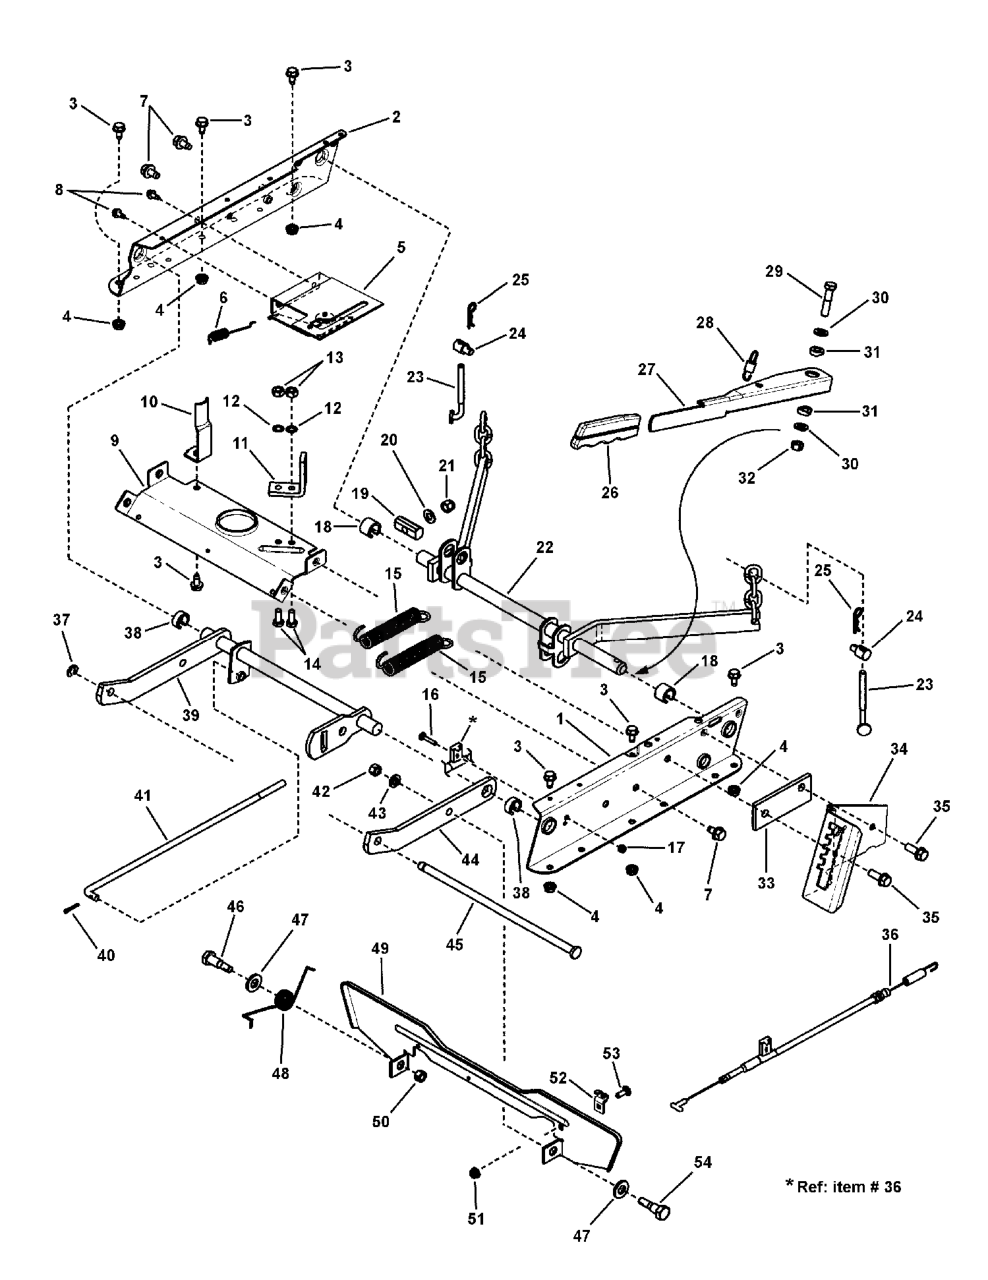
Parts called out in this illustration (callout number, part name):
1	RAIL, Deck Lift, Left Hand
2	RAIL, Deck Lift, Right Hand
3	SCREW, 5/16-18 x 5/8" Hex Washer Self-Tap
4	NUT, 5/16-18 Hex Flange Lock, GR 5
5	KIT, Clutch Plate Assembly
6	SPRING, Latching
7	SCREW, 3/8-16 x 5/8" Hex Washer Self-Tap
8	SCREW, 5/16-18 x 1/2" Hex Washer Self-Tap
9	BRACE, Top
10	GUIDE, Belt
12	WASHER, 5/16" Internal Tooth Lock
13	NUT, 5/16-24 Hex
14	SCREW, 5/16-24 x 3/4" Hex Head Cap, GR 5
15	SPRING, Assist
16	BOLT, #10-24 x 1" Flat Head Square Neck
17	NUT, #10-24 Hex Nyloc
18	RING, Rear Lift Arm (Blue)
19	PIVOT, Leveling
20	WASHER, 3/8" Flat SAE
21	NUT, 3/8-24 Hex Nyloc
22	WELDMENT, Rear Lift Arm
23	ADJUSTER, Chain (5/16-18 thread)
24	SWIVEL, Adjustable
25	HAIR PIN, 3/32 x 1-1/2"
26	GRIP, Height Adjustment Lever
27	LEVER, Height of Cut
28	SPRING, Lever
29	SCREW, 3/8-24 x 1-3/4" Hex Head Cap, GR 5
30	WASHER, 13/32 x 1-1/4" Flat
31	SPACER, Deck Lift
32	NUT, 3/8-24 Hex Center Lock
33	SPACER, Detent
34	DETENT, Height Adjust
35	SCREW, 3/8-16 x 1" Hex Washer Self-Tap
36	CABLE ASSEMBLY, No Reverse in Mow
37	RING, .438 External Retaining
38	RING, Front Lift Arm (Red)
39	WELDMENT, Front Lift Arm
40	PIN, 1/8 x 3/4" Cotter
41	ROD, Leveling (3/4-24 thread)
42	NUT, 3/8-24 Hex, GR B
43	WASHER, Flat 13/32" ID x 1.25" x 1/8" Thick ZP
44	ARM, Front Lift
45	ROD, Deck Support (Front Lift Arm to Front End)
46	SHOULDER BOLT, 3/8-24 x 9/16"
47	WASHER, 1/2" Flat SAE
48	SPRING, Pedal
49	FOOT PEDAL, Blade Stop Control
50	NUT, 3/8-24 Hex Center Lock
51	NUT, 1/4-20 Hex Flange Lock, GR 5
52	CLIP, Cable
53	BOLT, 1/4-20 x 3/4" Square Neck Carriage, GR 5
54	SHOULDER BOLT, 3/8-24 w/Nylon Patch, GR 5
